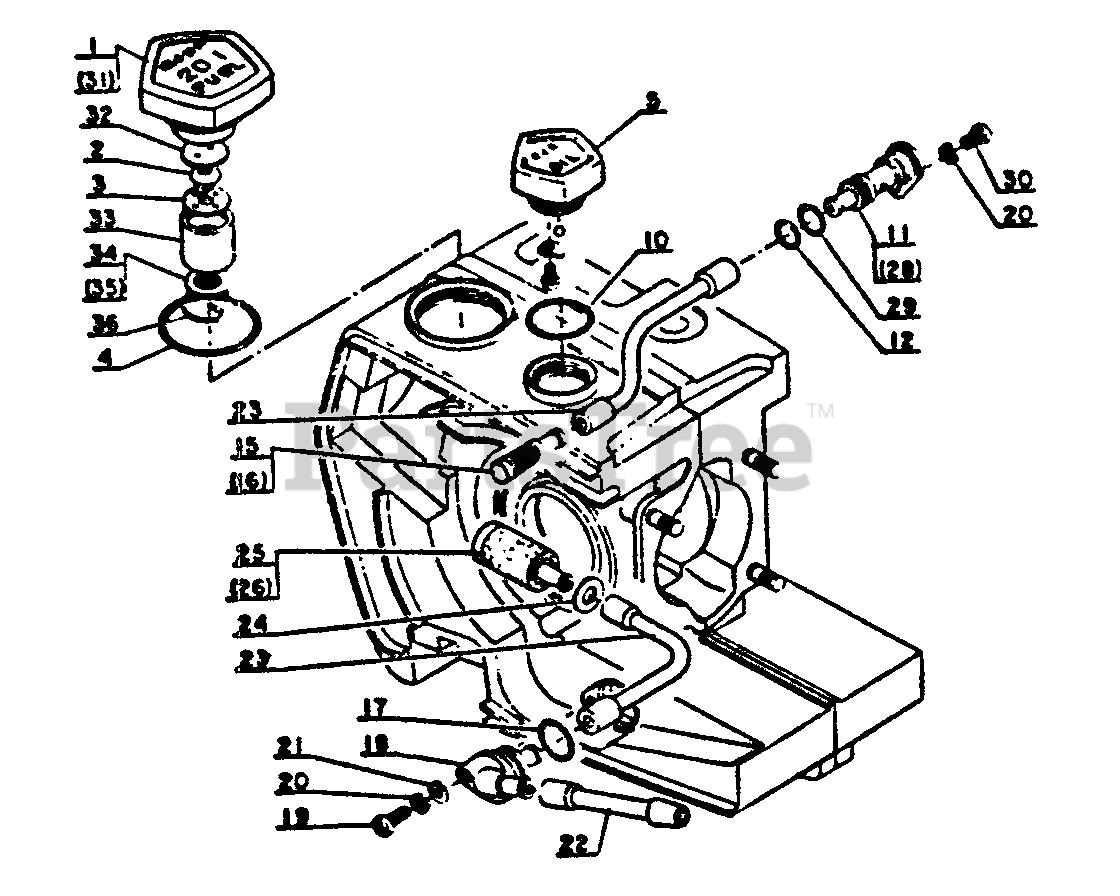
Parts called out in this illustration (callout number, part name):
1	CAP
3	HOLDER, VENT
5	CAP, OIL TANK
10	GASKET, CAP
11	CONNECTOR, PIPE
12	O-RING
15	FILTER, OIL
17	O-RING
18	CONNECTOR, PIPE
19	SCREW - 4X14
20	LOCKWASHER - 4
21	WASHER - 4
22	PIPE - FUEL -- OUTER
23	PIPE
24	WASHER - 6
25	FILTER, FUEL
29	O-RING
30	SCREW - 4X10
34	FILTER
36	RING, RETAINING
